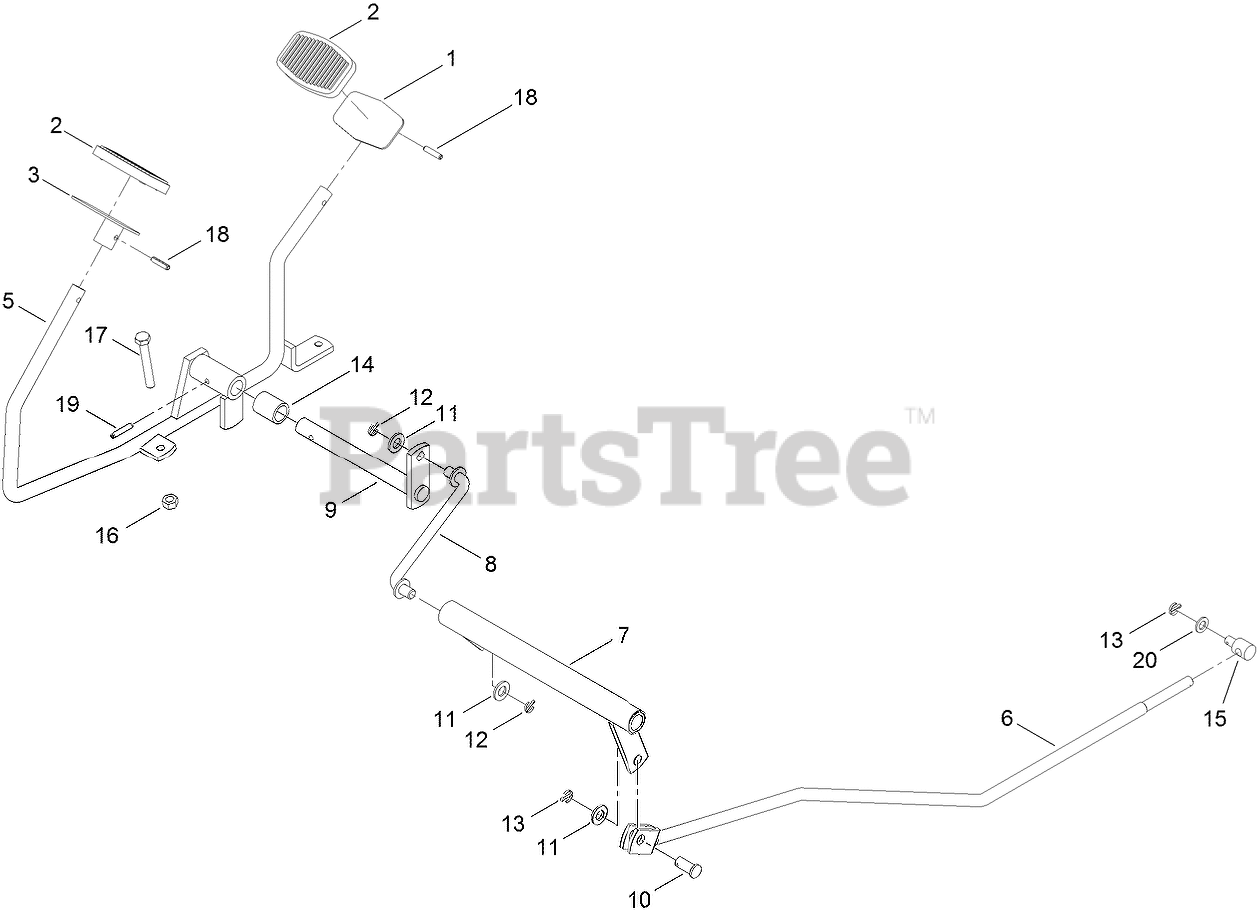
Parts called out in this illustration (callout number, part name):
1	PEDAL-REAR, TRAVEL
2	PAD-PEDAL
3	PEDAL-TRAVEL, FRONT
5	ROD-TRAVEL
6	ROD-TIE
7	SHAFT-DIAGONAL
8	LINK-FORMED
9	SHAFT-DIAGONAL
11	WASHER-FLAT
12	PIN-COTTER
13	PIN-COTTER
14	SPACER
16	NUT-HEX
17	SCREW-HH
18	PIN-SPRING
19	PIN-SPRING
20	WASHER
